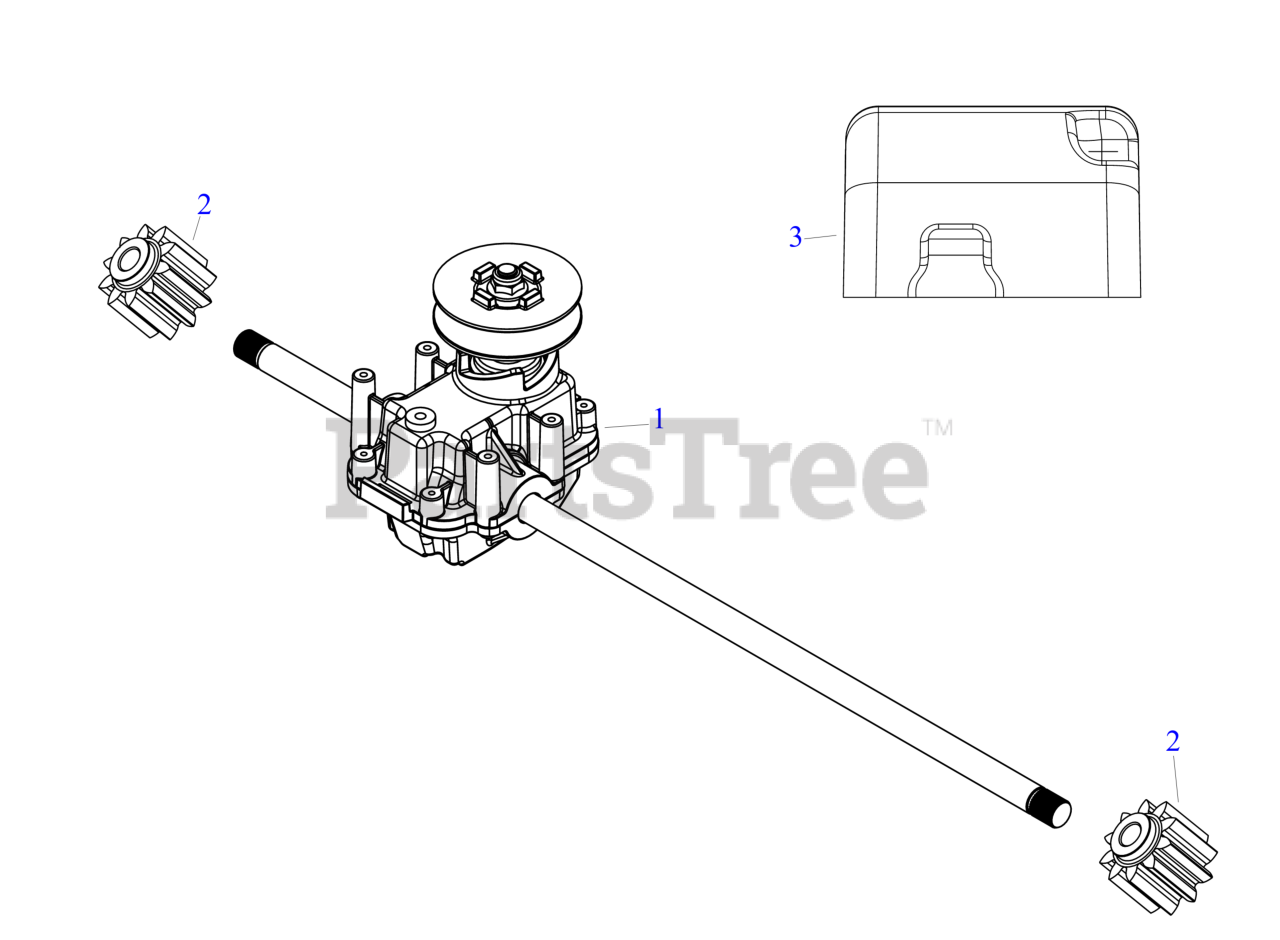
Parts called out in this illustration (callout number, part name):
1	TRANSMISSION
2	SPUR GEAR 10T
3	TRANSMISSION COVER
